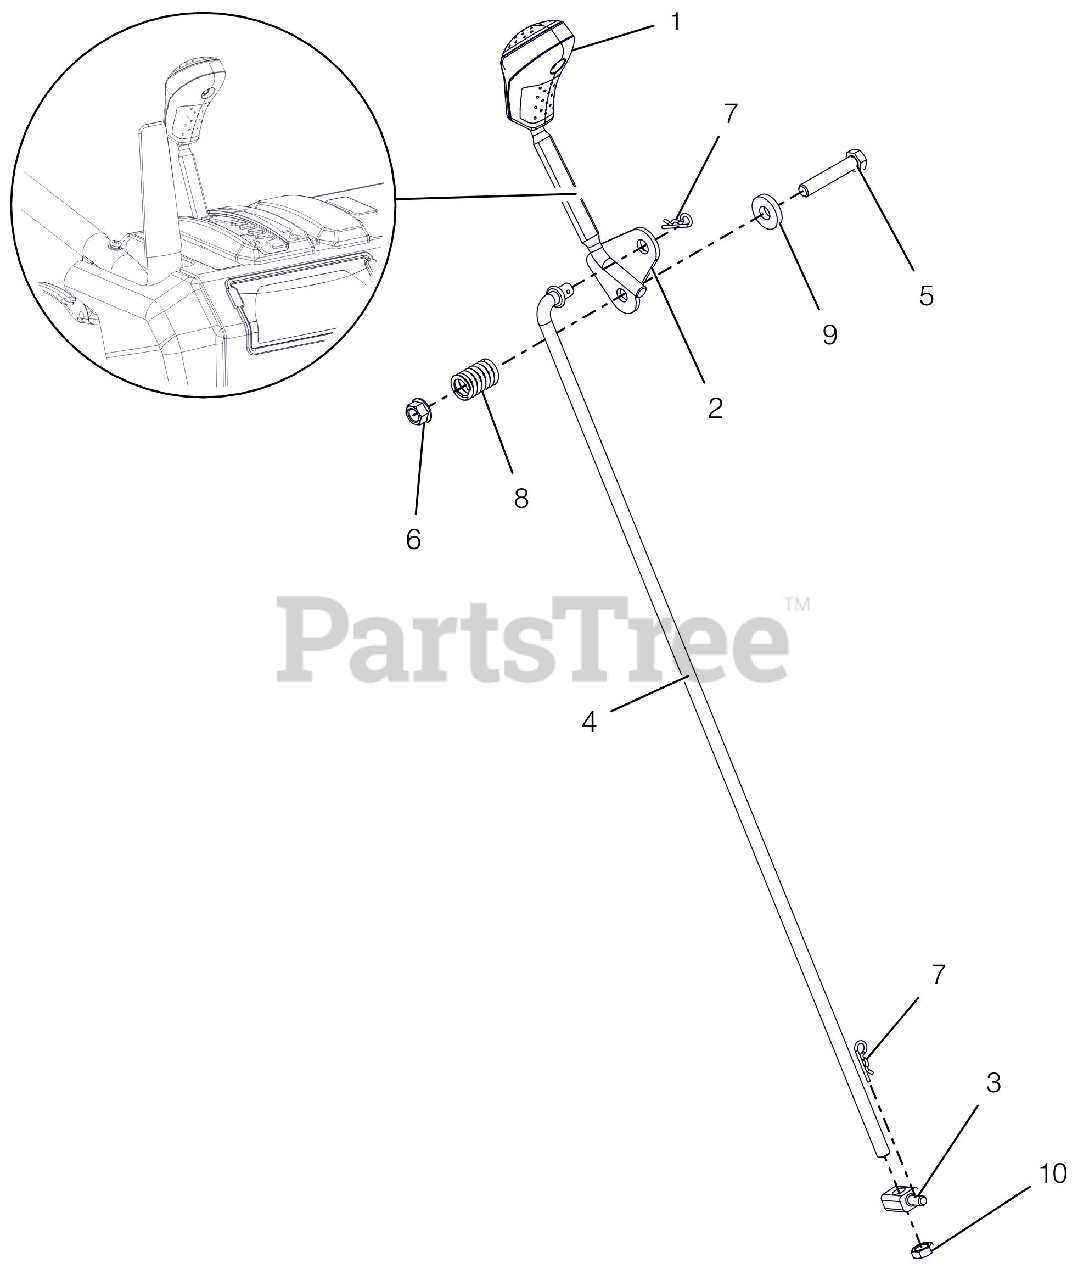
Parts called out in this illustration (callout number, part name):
1	KNOB, CONTROL, DASH
2	WELDMENT,LG DASH SPEED CONTROL
3	PIVOT,SHIFT ROD .375-16(TRUNN)
4	ROD, SHIFT-PRO
5	@BLT-HEX .38-16X2.00 GR5 YWZC
6	@NUT-LK-TOP-FLG .38-16 YWZC
7	PIN-HAIR INT .08X.18X1.18 YWZC
8	SG-COMP .125X.781X1.250
9	WSHR-FL-STL .406X1.00X.188 YWZ
10	NUT-HEX-JAM .375-16 YWZC
